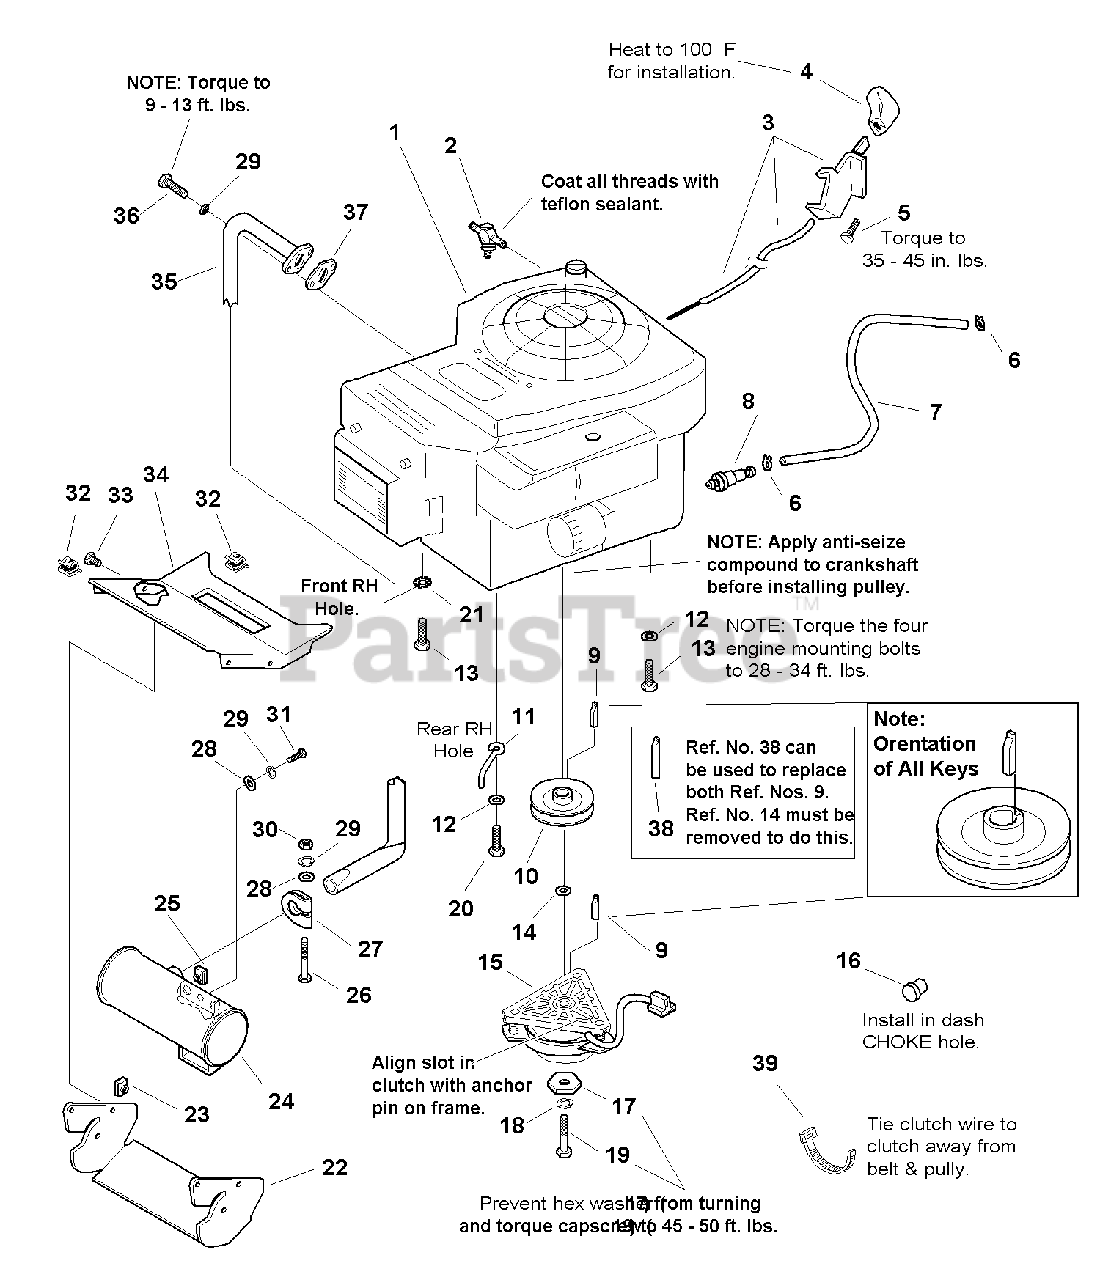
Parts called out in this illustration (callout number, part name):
1	ENGINE, 17HP Briggs & Stratton Vanguard
2	DRAIN VALVE, Oil
3	CONTROL, Throttle, Includes Cable
4	KNOB, Throttle Control
5	CAPSCREW, Hex Washer Head, Plastite, 1/4 x 1/2
6	CLAMP, Hose
7	HOSE, Fuel, 1/4 ID x 1/2 OD x 38" Long
8	FILTER, Fuel (1691732 only)
9	KEY, Hi-Pro
10	PULLEY ASSY. (14 HP Hydro Only)
11	STOP-BELT .213WIRE 3.12 ,0.75 BLK
12	WASHER, 3/8, .41 ID x .87 OD x .08 THK
13	SCREW, Hex, Taptite, 3/8-16 x 1-1/2 (Mfg. No.1691535,1691537, 1691551)
14	WASHER, 1, (As Required for All Front, As Required for K62 Rear)
15	CLUTCH, Electric Ogura
16	FASTENER, Panel
17	WASHER, Hex
18	LOCKWASHER, Spring, 7/16
19	CAPSCREW, Hex Head, 7/16-20 x 2-1/2
20	CAPSCREW, Hex Head, Taptite, 3/8-16 x 1-1/2 (For 1692768)
21	WASHER, Lock, External Tooth, 3/8
22	DUCT, Muffler, Bottom
23	NUT, Speed Lug Type, 1/4-20
24	MUFFLER ASSEMBLY
25	NUT, Speed Lug Type, 5/16-18
26	BOLT, Carriage, Short Neck, 5/16-18 x 2-3/4, GR5
27	CLAMP, Muffler, 1.312 Dia.
28	WASHER, 5/16, .34 ID x 3/4 OD x .06 THK
29	WASHER, Lock Helical Spring
30	NUT, Hex, 5/16-18 NC-2B
31	CAPSCREW, Hex Head, 5/16-18 x 1, G5
32	CLIP, Wire, 1/8 Dia.
33	CAPSCREW, Hex Flange, Whiz Lock, 1/4-20 x 5/8
34	DUCT, Top, Muffler
35	PIPE, Exhaust
36	CAPSCREW, Hex Socket Head, 5/16-18 x 3/4
37	GASKET, Muffler (12 HP Briggs & Stratton only)
38	KEY, Hi-Pro, 1/4 x 2
39	TIE, Self Locking, 3-5/8 LG
